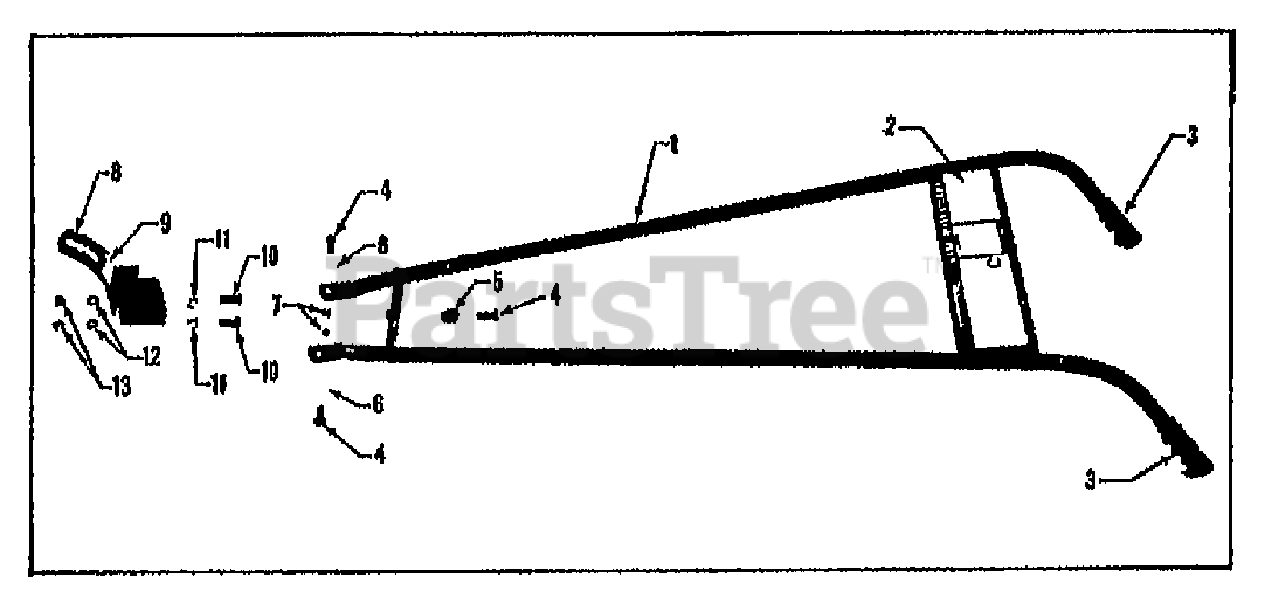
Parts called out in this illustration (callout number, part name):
1	ASSM-HANDLEBAR CULT (INCL. 60151 & 9471)
2	DECAL-CONTROL PANEL
3	GRIPS-HANDLEBAR
4	SCR-HH 3/8-16X1.0 G5 ZP (HANDLEBAR HEIGHT ADJ. ALSO MOUNTS HANDLEBAR TO CHASSIS)
5	WASHER-#1.75X.625X.120
6	WASHER-FLAT 3/8 SAE
7	NUT-LOCK 3/8-16 NYLON ZP
8	PLATE-H/B ADJ W/DECAL #60075
9	DECAL-HANDLEBAR ADJUST
10	SCR-HH 3/8-16X1.0 G5 ZP (ATTACHES HANDLE- BAR HEIGHT ADJ. PLATE TO CHASSIS)
11	WASHER-LK .375 @ DEPL
12	WASHER-.734X.375X.065 ZP
13	NUT-HEX 3/8-16 ZP
